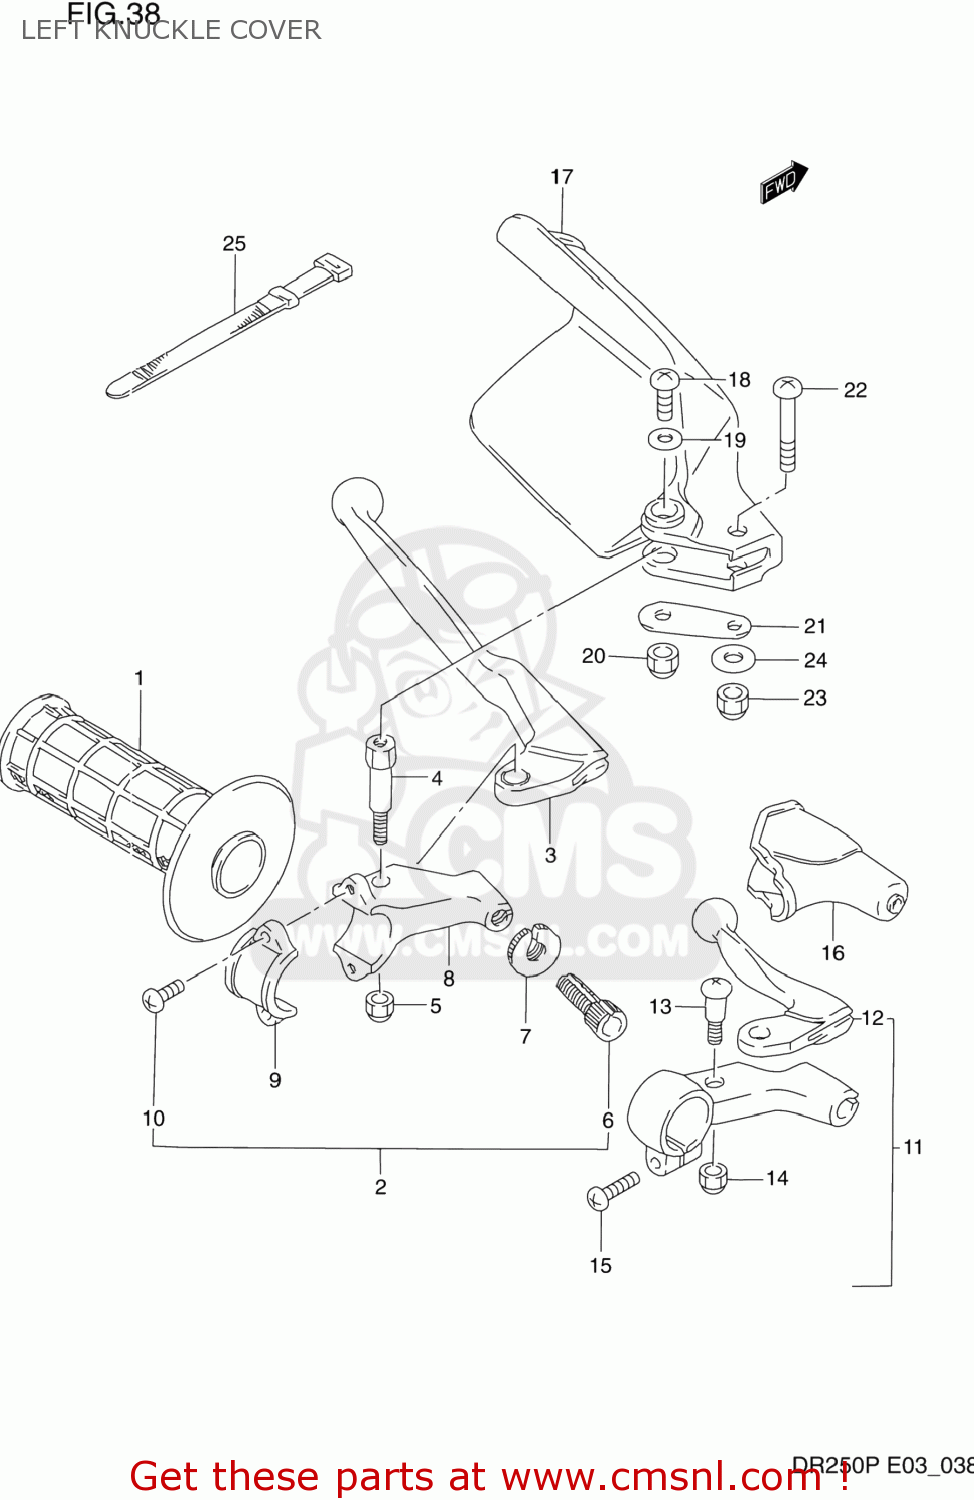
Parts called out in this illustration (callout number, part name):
1	GRIP,L
2	LEVER ASSY,CLUTCH
3	LEVER,CLUTCH
4	BOLT,LEVER SET
5	NUT 6MM
6	ADJUSTER,CABLE
7	NUT,LOCK
8	HOLDER,CLUTCH LEVER
9	BRACKET,CLUTCH LEVER HOLDER
10	SCREW(5X14)
11	LEVER ASSEMBLY,DECOMPRESSION
12	LEVER,DECOMP
13	BOLT,LEVER PIVOT
14	NUT
15	SCREW
16	COVER,DECOMP LEVER DUST
17	COVER,KNUCKLE,LEFT
18	SCREW(5X10)
19	WASHER (5.5X16X1.2)
20	NUT 6MM
21	PLATE,KNUCKLE COVER,L LWR
22	SCREW
23	NUT 6MM
24	WASHER (6.5X17X1.6)
25	CLAMP(L:120)
